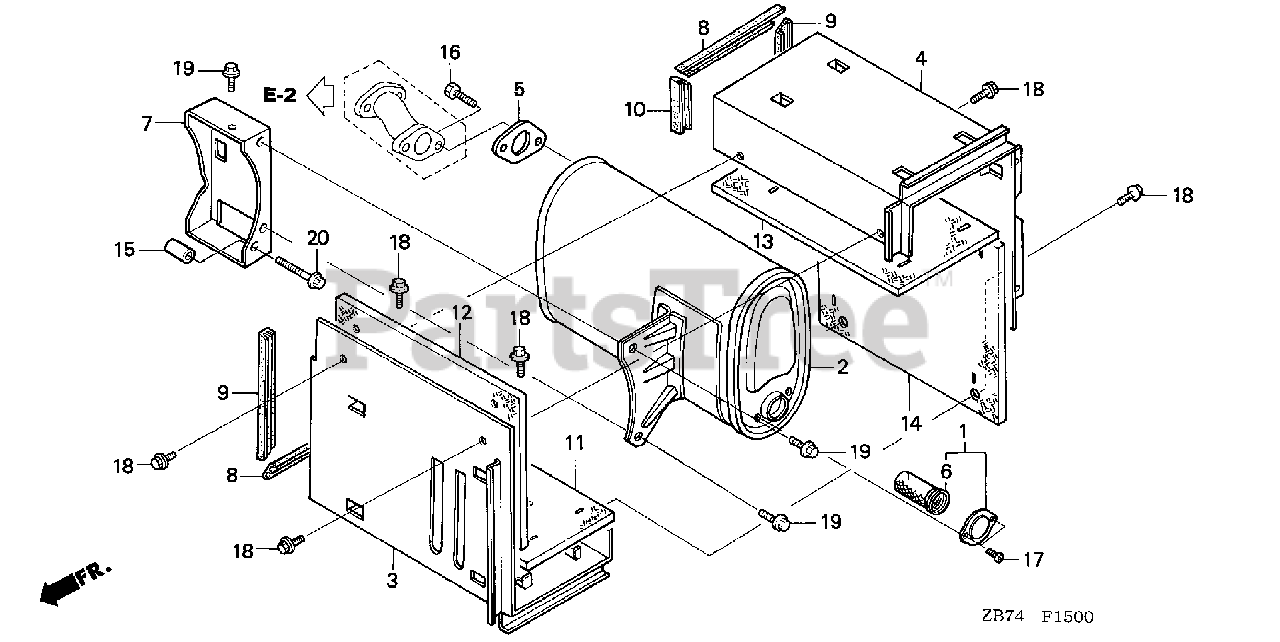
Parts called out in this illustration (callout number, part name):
1	ARRESTER SET, SPARK
3	DUCT, MUFFLER (LOWER)
4	DUCT, MUFFLER (UPPER)
5	GASKET, EX. PIPE
6	ARRESTER, SPARK
7	STAY, MUFFLER
8	SEAL, MUFFLER DUCT (A)
9	SEAL, MUFFLER DUCT (B)
10	SEAL, MUFFLER DUCT (C)
11	INSULATOR A, MUFFLER DUCT (LOWER)
12	INSULATOR B, MUFFLER DUCT (LOWER)
13	INSULATOR A, MUFFLER DUCT (UPPER)
14	INSULATOR B, MUFFLER DUCT (UPPER)
15	COLLAR, MUFFLER STAY
16	BOLT, HEX. (8X28)
17	SCREW, PAN (6X10)
18	BOLT, FLANGE (6X12)
19	BOLT, FLANGE (8X16)
20	BOLT, FLANGE (8X40)
